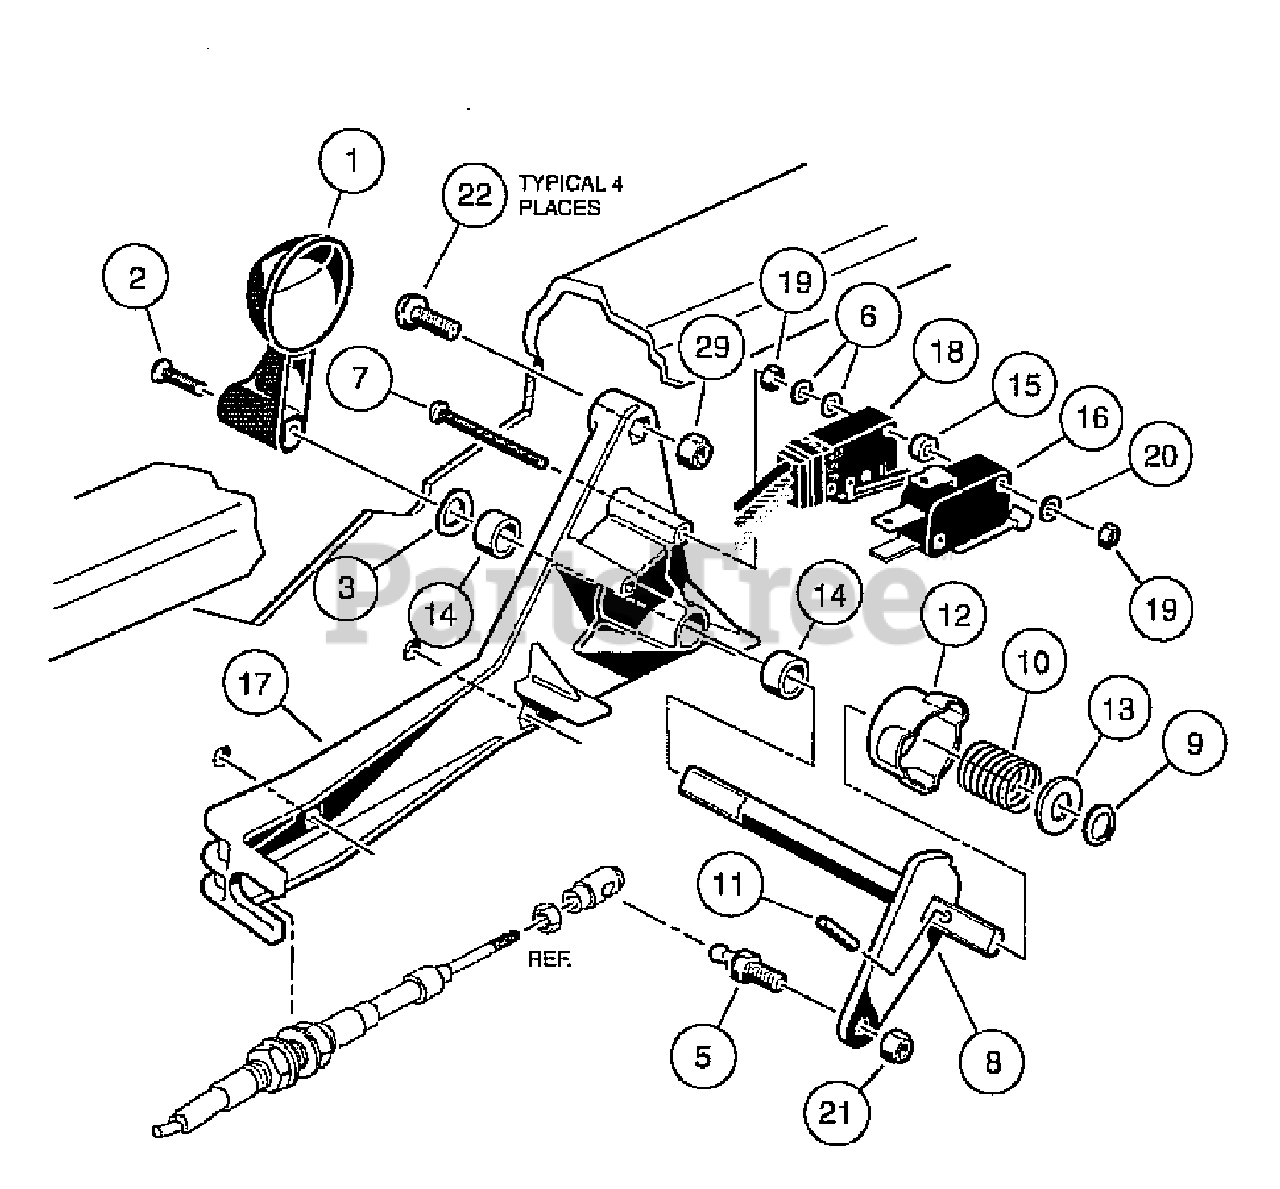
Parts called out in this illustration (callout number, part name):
1	Handle, FNR
2	Screw, #8-32 X 0.63 Machine
3	Washer, Wave
4	Assembly, FNR Shifter
5	Stud, 1/4-28 X 0.560 Ball
6	Washer, #4 Flat
7	Screw, #4-40 Machine
8	FNR Bell Crank Weldment
9	Ring, 0.338" Internal Retaining
10	Spring, FNR Cam
11	Pin, 1/8 X 1/2 Roll
12	Neutral Lockout Cam Kit
13	Washer, 0.38" Id Delrin Flat
14	Bushing, Secondary Weight, Split
15	Washer. #4 Nylon Flat
16	Switch, Limit
17	FNR Shifter Base
18	Assembly, Switch, Limit
19	Nut, #4-40 Hex Machine
20	Lockwasher, #4 Helical Split
21	Locknut, 1/4-28 Nylon Insert
22	Screw, 1/4-20 X .75 Trs Hd Mch
